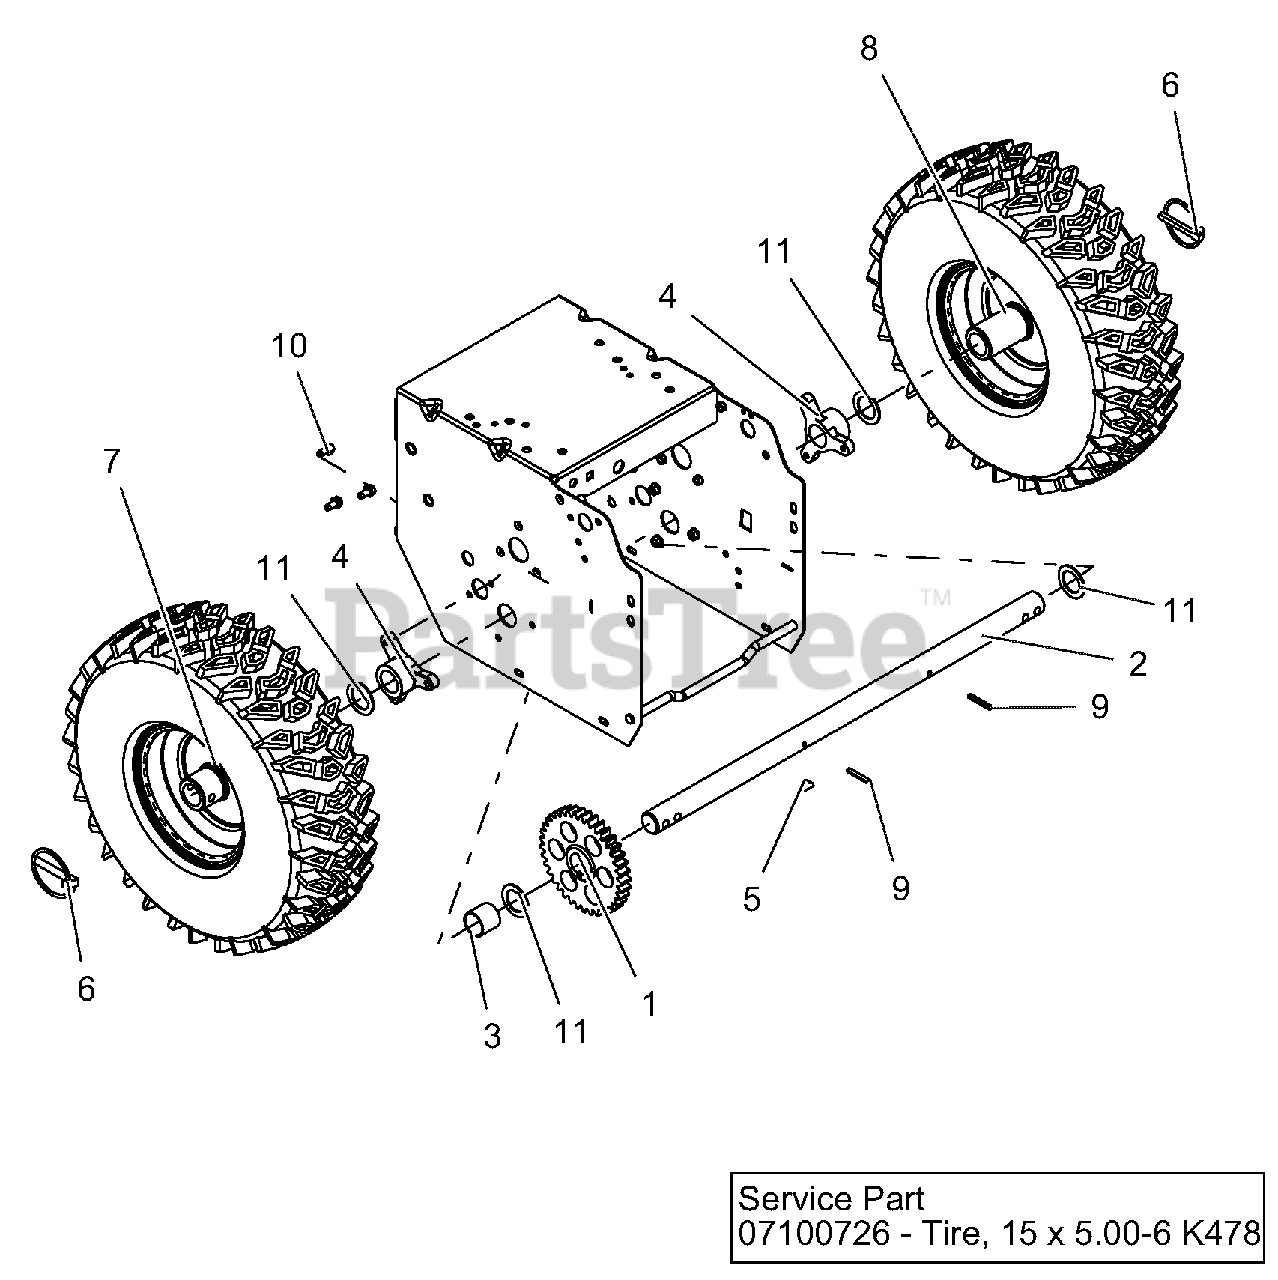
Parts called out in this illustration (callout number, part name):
1	GEAR, SPUR
2	AXLE, 1.00" SOLID
3	BSHG-SLV, 1.012X1.125X1.00
4	BUSHING, AXLE
5	KEY-WDRF .25X.750X.313 SAE91
6	PIN-LOK .31X2.00
7	TIRE/WHEEL, RH 15X5.00-6 PIN
8	TIRE/WHEEL, LH 15X5.00-6 PIN
9	PIN-ROLL .188X1.25
10	SCR-TAP .25-20X.50 HWH TR YWZ
11	WSHR-FL-STL 1.010X1.505X.062YZ
